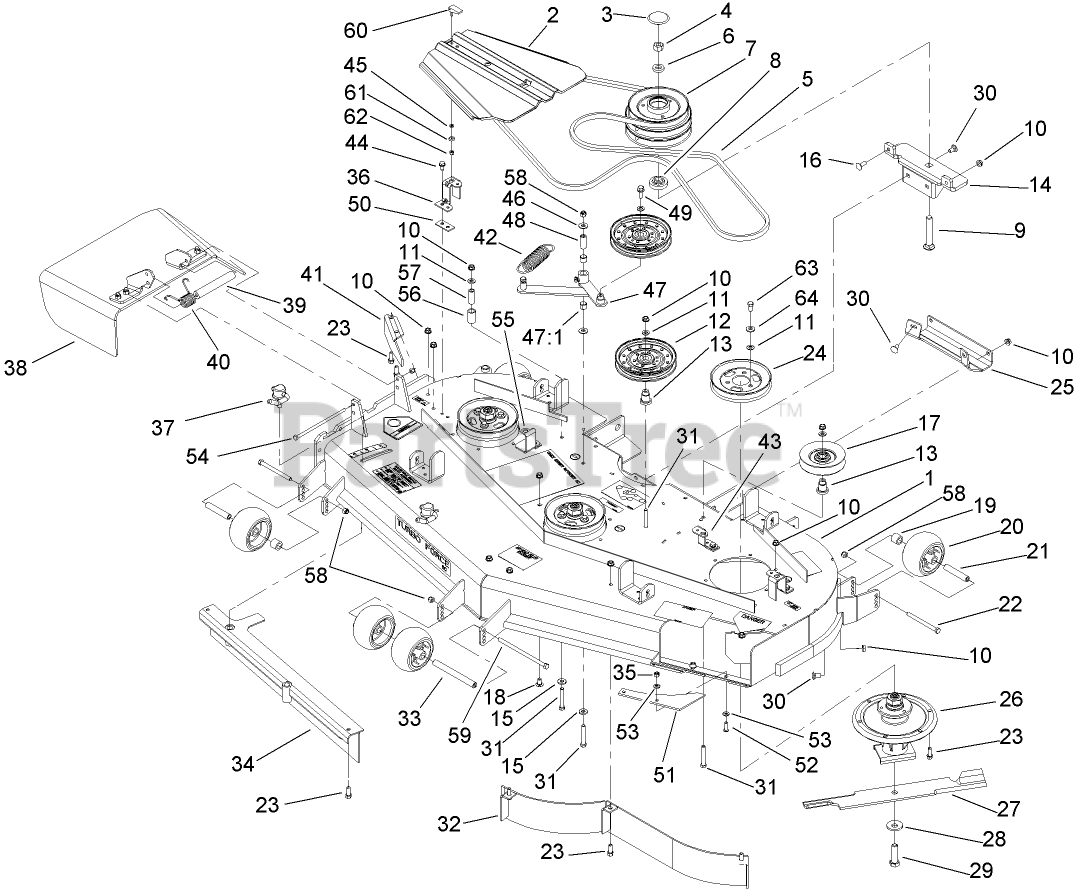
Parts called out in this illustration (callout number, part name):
1	DECK DECAL ASM
2	COVER-BELT
3	CAP-PLASTIC
4	NUT-HEX
5	BELT-V
6	SPACER
7	PULLEY AND BEARING ASM
8	SPACER-FLANGED
9	BOLT-CARRIAGE
10	NUT-HHF, WHIZ
11	WASHER-FLAT
12	Idler-Flat
13	MOUNT-PULLEY
14	MOUNTING BRACKET ASM
15	WASHER-BELLEVILLE
16	BOLT-CARR
17	PULLEY-IDLER
18	SCREW-CARR
19	TUBE-SPACER
20	ROLLER-SCALP, ANTI
21	TUBE-SPANNER
22	SCREW-HH
23	SCREW-HWH
24	Pulley
25	Plate-Skid
26	SPINDLE ASM
27	BLADE-HI FLOW
28	Washer-Blade Bolt, Heavy
29	SCREW-BLADE
30	SCREW-CARR
31	SCREW-HH
33	SPACER-WHEEL
35	NUT-LOCK, NI
36	BRACKET-COVER
37	LEVER ASM
38	RUBBER DEFLECTOR ASM
39	SPACER
40	SPRING-TORSION
41	BAFFLE-DISCHARGE
42	SPRING-EXTENSION
43	BRACKET-COVER, TALL
44	SCREW-HWHTF
45	WASHER
46	WASHER-FLAT
47	IDLER ARM ASM
47:1	SLEEVE-BEARING
48	BUSHING
49	SCREW-HHF
50	SPACER-COVER, BELT
51	PLATE-TURBO
52	SCREW-HSBH
53	WASHER-SPRING
54	SCREW-HH
55	BRACKET-COVER
56	SPACER-RUBBER
57	SPACER-PIVOT, IDLER
58	NUT-LOCK, NI
59	SCREW-HH
60	HANDLE-LATCH, SWELL
61	BUSHING-LATCH, SWELL
62	NUT-LOCK, HH
63	SCREW-HH
64	WASHER-BELLEVILLE
